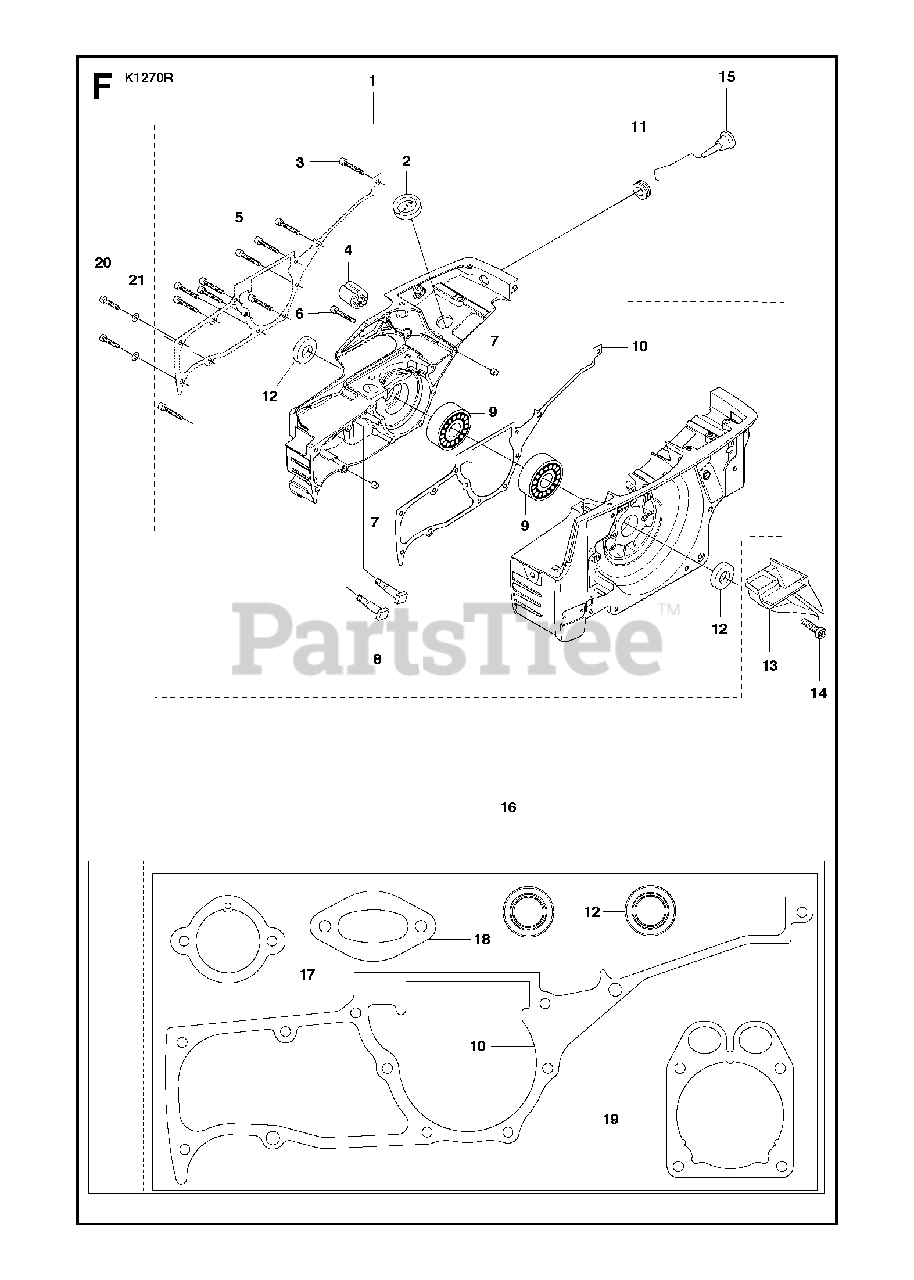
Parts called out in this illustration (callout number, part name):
3	SCREW ITXSCM
4	ANTIVIBRATION ELEMENT
5	SCREW ITXSCM
6	SCREW ITXSCM
7	GUIDE BUSHING
9	BALL BEARING
12	SEALING RING
14	SCREW ITXSCM
16	GASKET KITIncl. 10, 12, 17-19
20	SCREW ITXSCM
